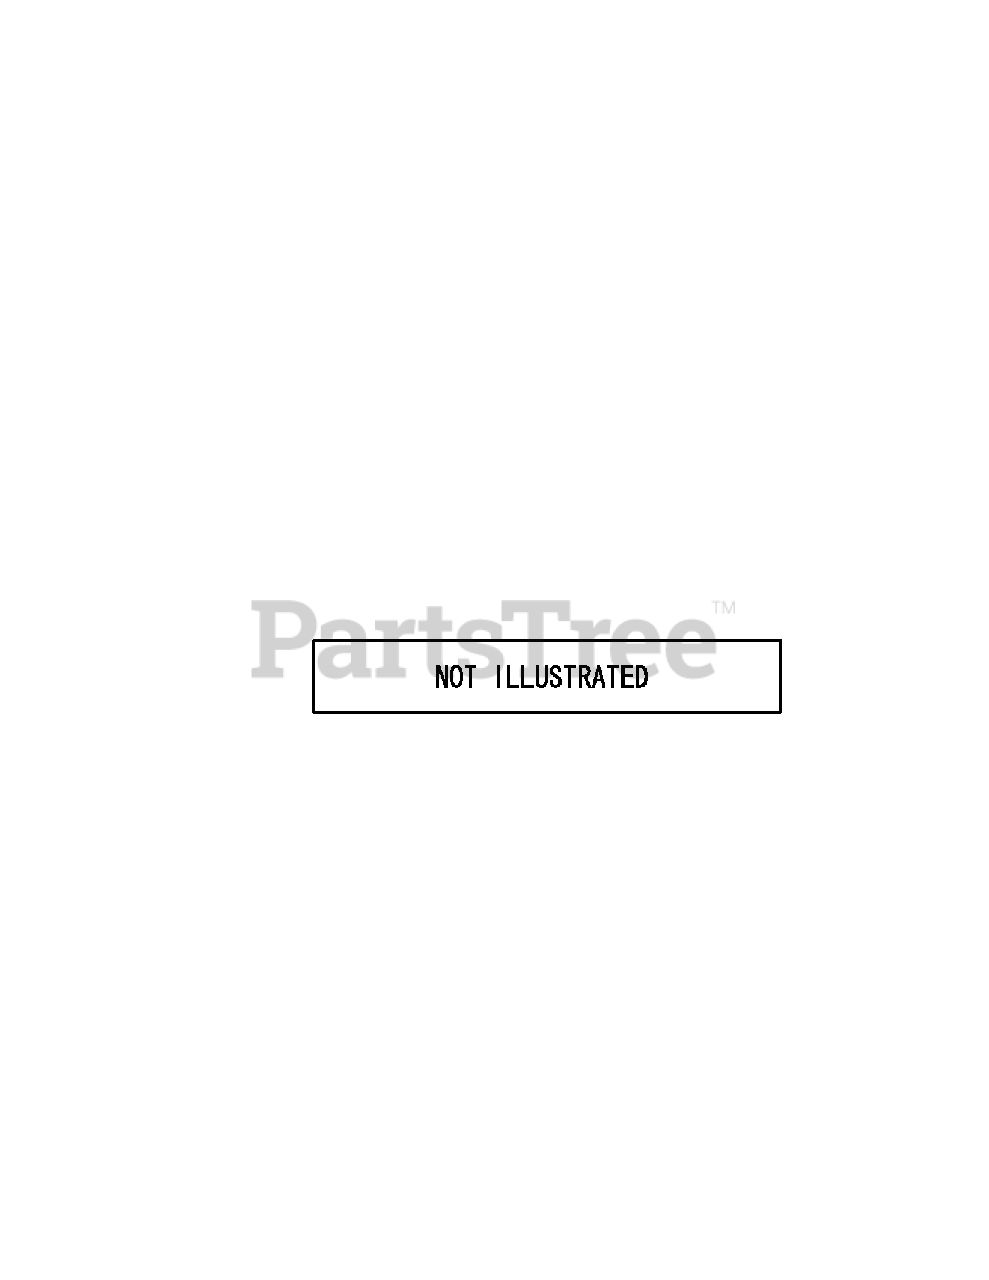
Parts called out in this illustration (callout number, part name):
1	Short Block Assy
2	Cylinder Block Cmp
3	Case Assy, Oil Seal
6	Crankshaft Assy
8	Pin, Piston(D26,L70)
9	Rod Assy, Connecting
10	Gear Assy, Idle
12	Bolt 8X 14 Plated
